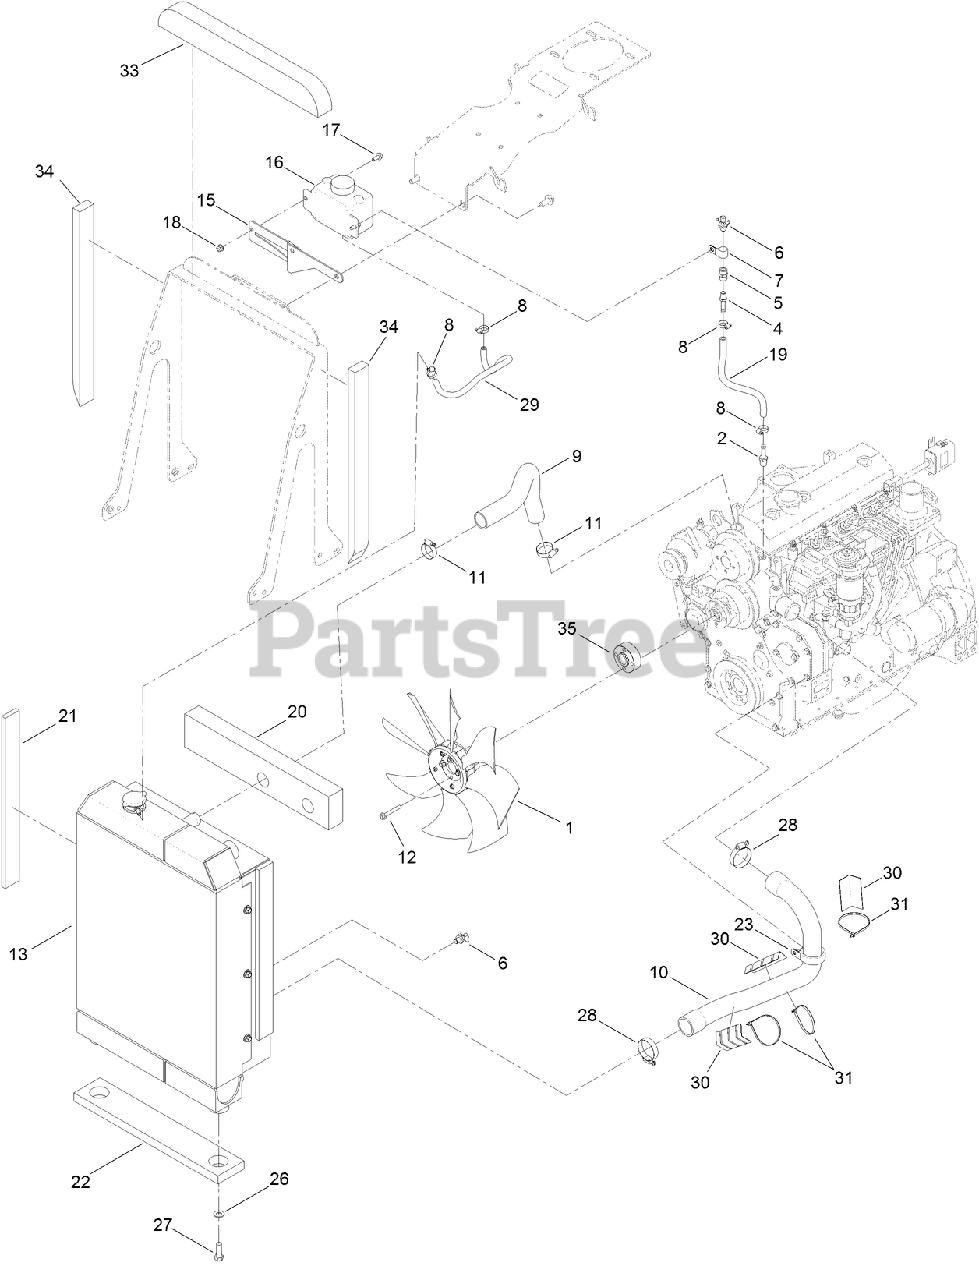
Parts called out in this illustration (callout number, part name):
2	STEM-STRAIGHT, BEAD
4	STEM-STRAIGHT, BEAD
5	COUPLING-PIPE (NPTF)
6	VALVE-SHUTOFF
7	CLAMP-R
8	CLAMP-HOSE
9	HOSE-RADIATOR, UPPER
10	HOSE-RADIATOR, LOWER (MOLDED)
11	CLAMP-HOSE
12	SCREW-FLANGE
13	COOLING ASM
15	MOUNT-TANK, OVERFLOW
16	TANK-Overflow
17	SCREW-HHF
18	NUT-TORQUE, PREVAILING
19	HOSE-COOLANT
20	SEAL-FOAM
21	SEAL-FOAM
22	SEAL-FOAM
23	CLAMP-R
26	WASHER-FLAT
27	SCREW-HH
28	CLAMP-HOSE
29	HOSE-FUEL
30	PROTECTOR-HOSE
31	TIE-CABLE
33	FOAM-HOOD, TOP
34	FOAM-HOOD, SIDE
